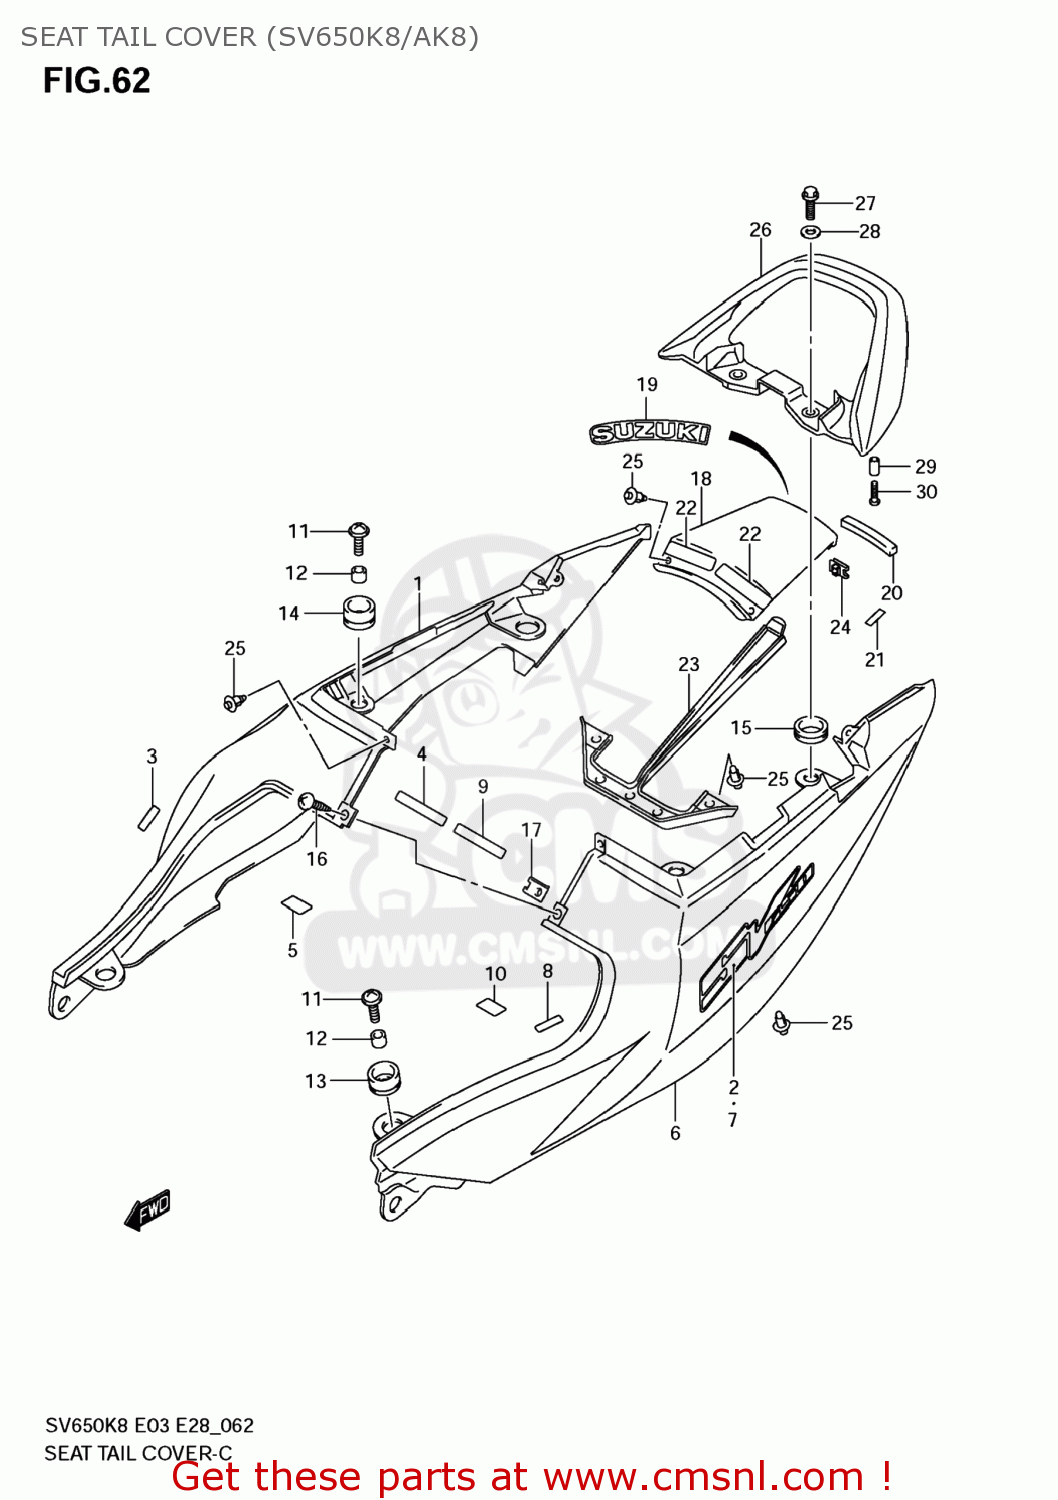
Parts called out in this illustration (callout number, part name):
1	COVER,SEAT TAIL,R(BLUE)
2	EMBLEM,SEAT TAIL COVER
3	TAPE,COVER
4	TAPE,SEAT TAIL COVER NO.2 FR
5	PROTECTOR,FRAME COVER
6	COVER,SEAT TAIL,L(BLUE)
7	EMBLEM,SEAT TAIL COVER
8	TAPE,COVER
9	TAPE,SEAT TAIL COVER NO.2 FR
10	PROTECTOR,FRAME COVER
11	SCREW(6X25)
12	SPACER(6.5X10X9.4)
13	CUSHION
14	CUSHION,SEAT TAIL COVER CTR
15	CUSHION
16	SCREW
17	NUT
18	COVER,SEAT TAIL CTR
19	EMBLEM,SUZUKI
20	CUSHION,SEAT TAIL COVER CTR
21	TAPE,SEAT TAIL COVER
22	TAPE,COVER
23	COVER,SEAT TAIL RR
24	NUT
25	CLIP
26	HANDLE,PILLION RIDER
27	BOLT
28	WASHER(8.5X24X2.3)
29	SPACER(6.5X9X18)
30	SCREW(6X25)
